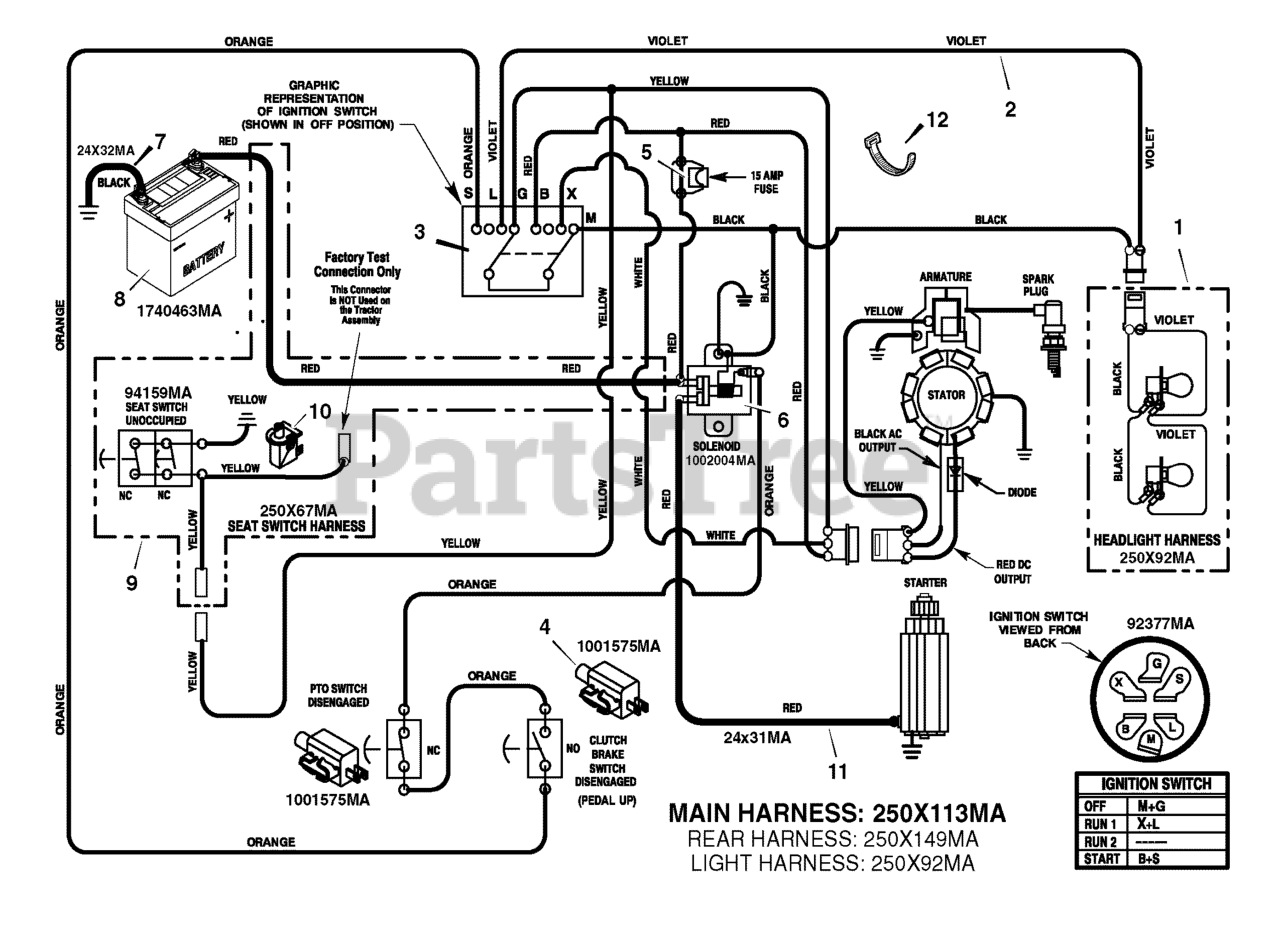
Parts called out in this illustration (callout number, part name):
1	Harness, Light Wire
2	Harness, Chassis Wire
3	Switch, Ignition
4	Switch, Limit
6	Solenoid
7	Cable, Battery Ground
9	Harness, Seat Switch Wire
10	Switch, Seat Sensor
12	Strap, Black Tie
